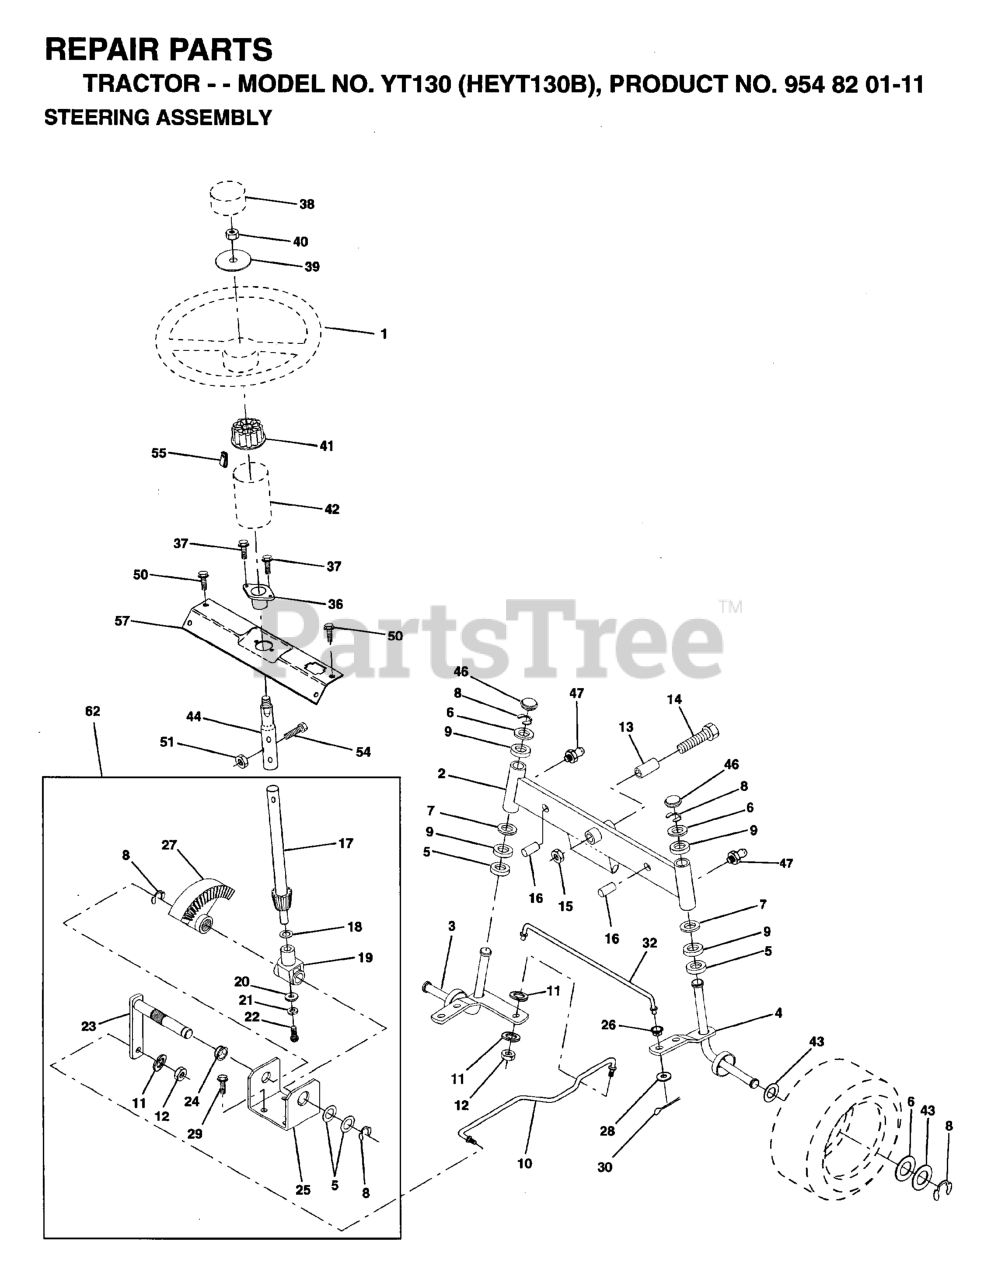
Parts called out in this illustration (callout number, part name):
1	STEERING WHEEL
3	SPINDLE LH
4	SPINDLE RH
5	THRUST WASHER
9	BRNG T
10	LINK.DRAG.SOL.BALL JT.20.064
11	WASHER, LOCK 3/8
12	NUT
13	BEARING
14	Bolt, Hex Head 5/8-11 x 3-1/2
15	NUT-LOC,FLANGE LT
17	SHAFT STEERING
18	THRUST WASHER
19	SHAFT,SUPPORT
20	WASHER
21	LOCKWASHER
22	SCREW,SPECIAL
23	SHAFT PITMAN
24	NYLINER T (7283A)
25	BRKT,STEERING
26	BUSHING LINK DRAG BLK LR
27	GEAR.SECTOR
28	WASHER
29	SCREW
30	COTTER PIN
32	TIE ROD
36	BUSHING-STRG LT
37	SCREW LT
38	INSERT,STR WHEEL
39	WASHER T
40	GRIPCO NUT
41	ADAPTER-WHEEL LT
42	BOOT, STEERING SHAFT
44	STEERING SHAFT
46	CAP.SPINDLE.BLACK
47	ZERK M
50	SCREW HEX CRT
51	NUT.71038.31-18.HEX.NYLOCK
54	BOLT.5/16-18X1-1/4 FULL.THREAD
57	SUPPORT STEERING SHAFT
62	KIT, STEERING ASSEMBLY
